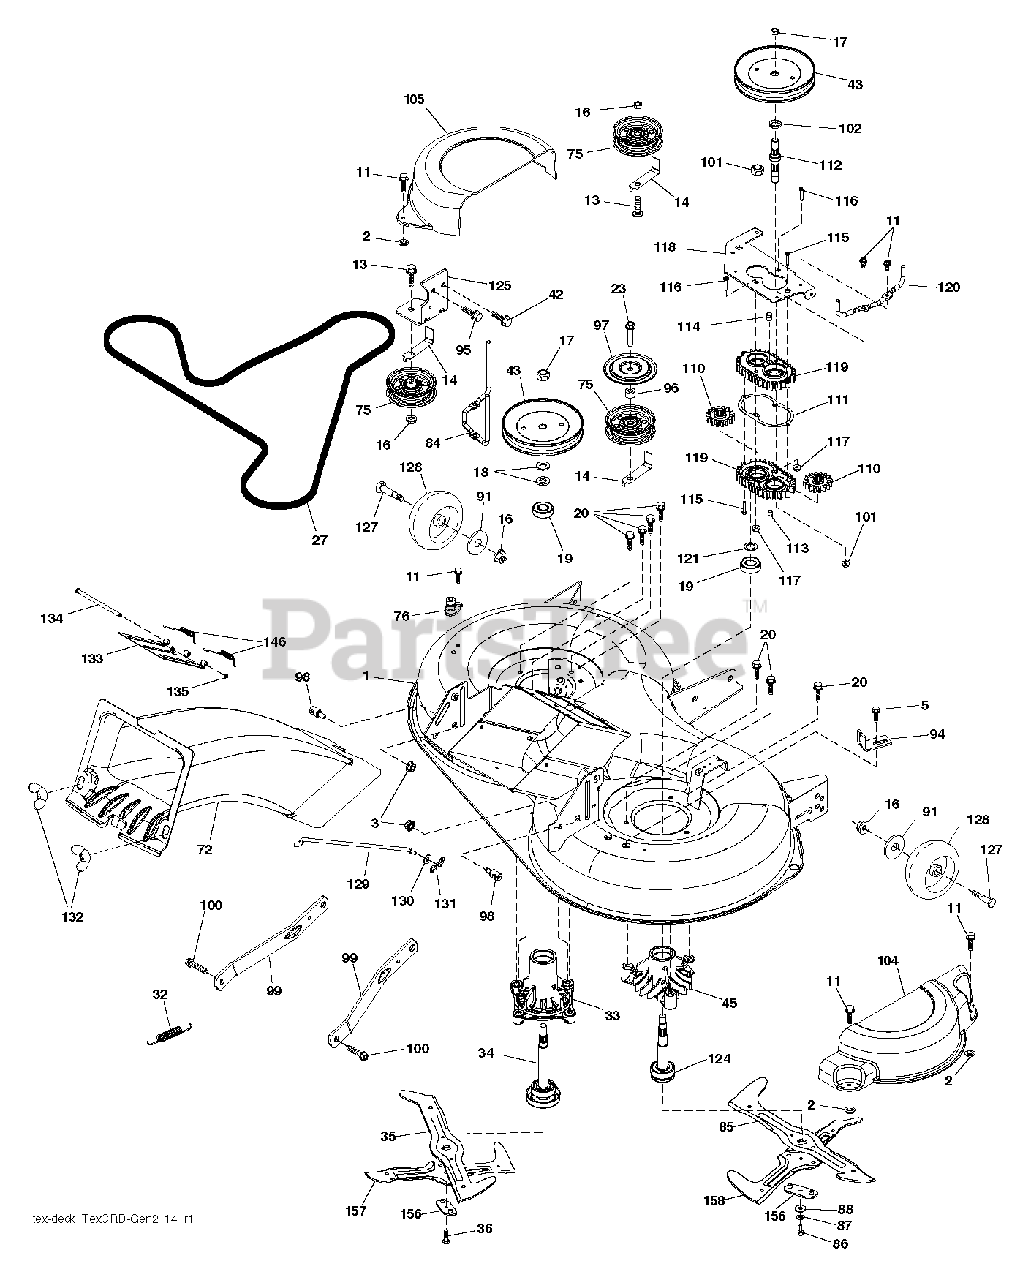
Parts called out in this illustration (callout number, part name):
2	PALNUT 1/4
3	NUT LOCK HEX FLANGE 5/16-18
5	BOLT.5/16HEX.WHS.HD
11	SCREW.1/4-20X5/8
13	BOLT.3/8-16X1.50
14	KEEPER, BELT IDLER
16	NUT LOCK FLG 3/8-16 UNC
17	NUT.FLANGE.LOCK.TOP
18	WASHER.SPACER.MANDREL
20	SCREW, WASHER HEAD
23	SCREW LT
33	HOUSING MANDREL
34	SHAFT.ASM.MDRL.N/GREASE.38
35	BLADE.3N1.LH.CRD
36	BOLT.WASHER.ASM.7/16-2
42	SCREW
45	HOUSING.MANDREL
75	FLAT IDLER PULLEY
76	PORT.WASHOUT
85	BLADE.3N1.RH.CRD
87	LOCKWASHER
88	WASHER.BLADE
94	BRKT.CLUTCH.CABLE
95	SCREW, 3/8-16X3/4
98	STUD.FASTNER.W/ANTI-ROTATE
99	ARM.SUSPENSION.MOWER.R
100	BOLT.SHOULDER
102	SPACER BEARING
117	NUT T
127	BOLT.SHOULDER.3/8-16X3-5/8
128	WHEEL. GUAGE RALLY
130	WASHER
131	PIN.COTTER.5/16.BOW TI
132	KNOB.HANDLE.3/8.TRI-POINT.BLAC
135	E-RING.5/16"
